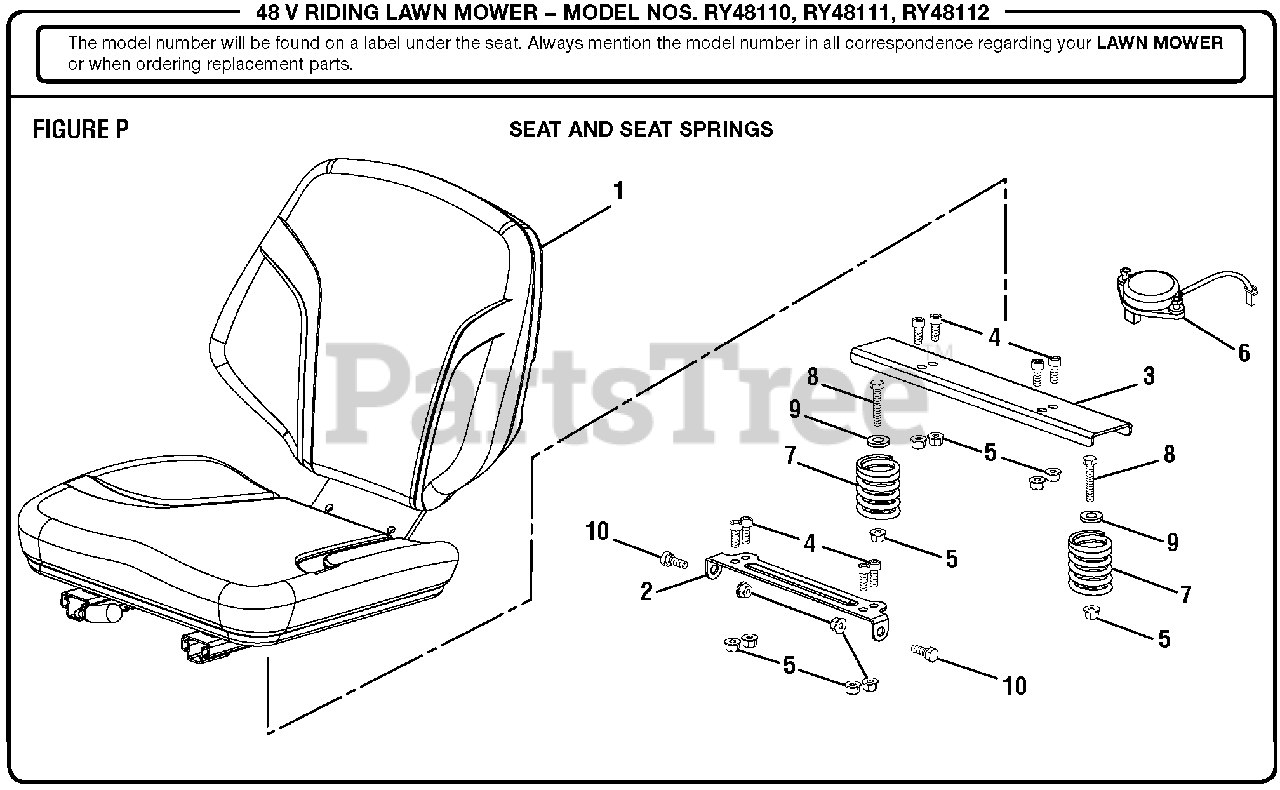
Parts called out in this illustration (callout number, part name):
2	Seat Base Plate
3	Seat Base Plate, Rear
4	Screw (M8 x 16 mm)
5	Flange Lock Nut (M8 x 1.25, Hex Hd.)
6	Seat Switch
7	Seat Spring
8	Bolt (M8 x 45 mm)
9	Washer (OD 24 x ID8.4 x 2t)
10	Shoulder Bolt (M8 x 20 mm)
